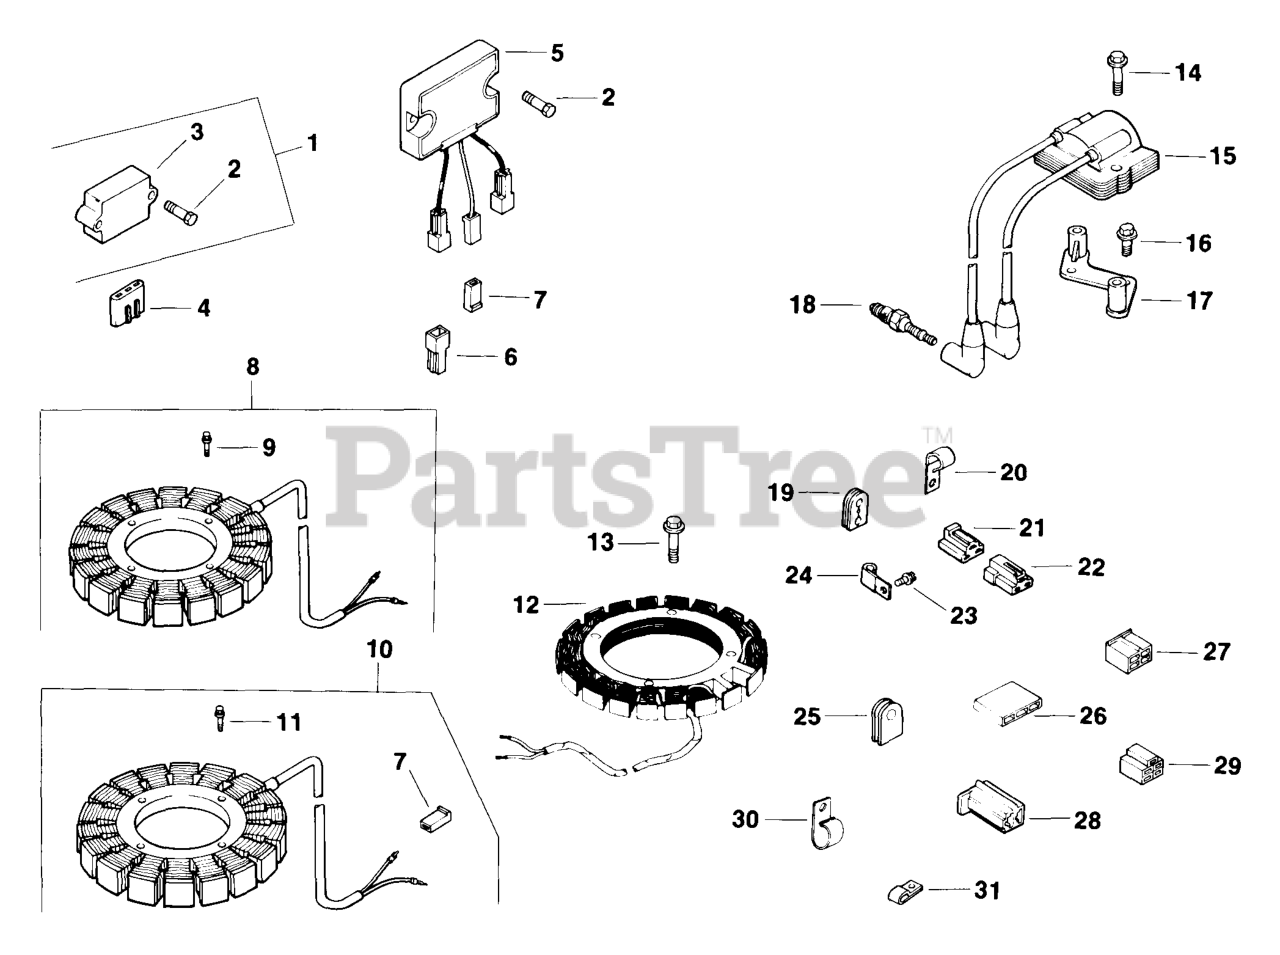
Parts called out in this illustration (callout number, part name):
1	Kit, Rectifier-Regulator
2	Screw, H.C. Sems 1/4-20x5/8"
3	Rectifier-Regulator
8	Kit, Stator
9	Screw, Hex. Wash. Hd. 10-24x3/4"
14	Screw, Hex. Wash. Hd. 1/4-20x1"
15	Module, Ignition
16	Screw, Hex. Wash. Hd. 1/4-20x1"
17	Bracket, Module
18	Spark Plug
21	Connector, Male (3 Contact)
26	Connector, Female (3 Contact)
